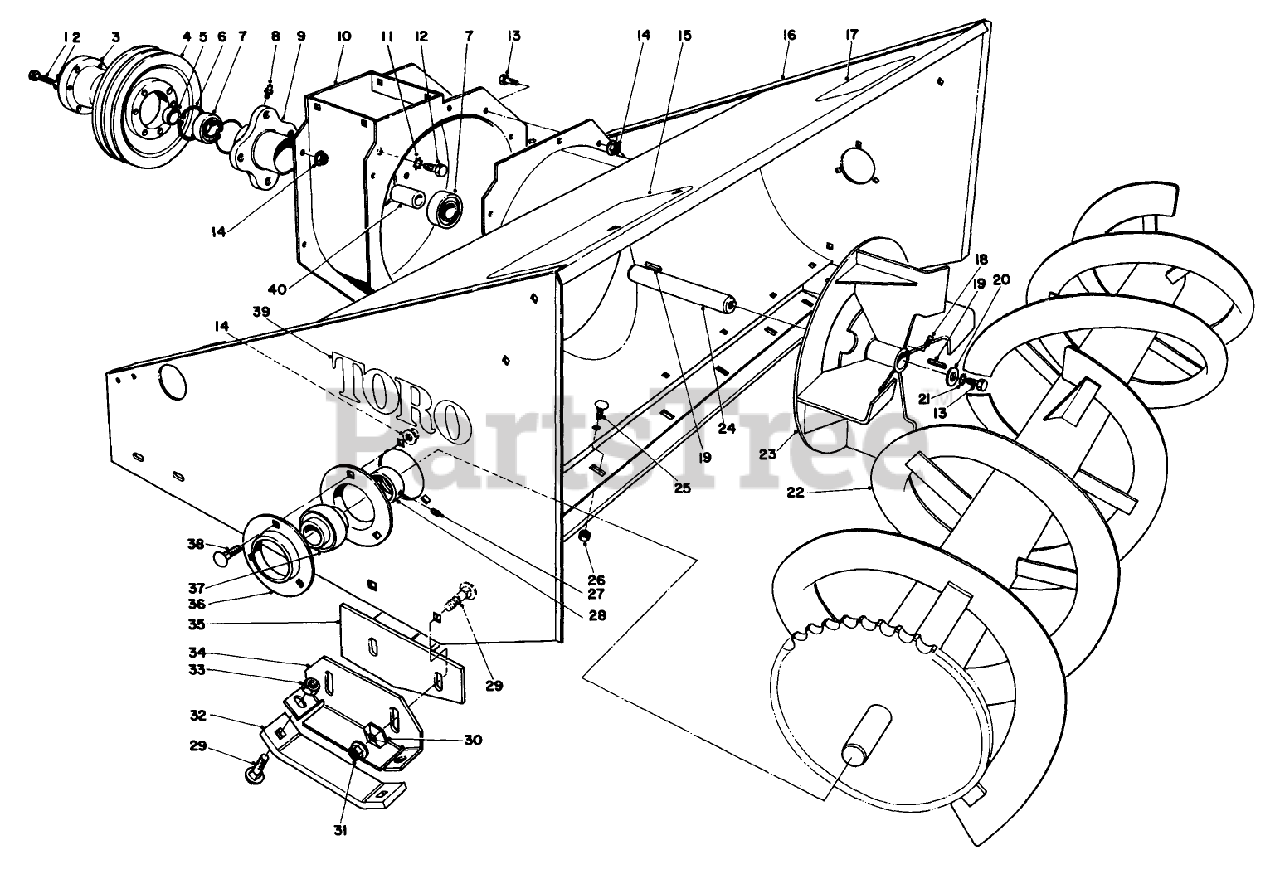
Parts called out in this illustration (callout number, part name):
1	SCREW-HH
2	WASHER-LOCK
3	Hub-"QD" (Incl. Ref.#1 & 2)
4	Pulley-"QD"
5	SPACER
6	RETAINING RING
7	BEARING
8	FITTING-LUBE, 45 DEG
9	SPINDLE HOUSING
10	BLOWER HSG WA
11	WASHER-LOCK, EXT
12	SCREW-HH
13	SCREW-HH
14	NUT-HF
15	Decal-Rear Weight
16	Auger Housing
17	Decal-Warning
18	SCREW-SET
19	Square Key
20	WASHER
21	WASHER-LOCK
22	Auger
23	IMPELLER WA 60096
24	IMPELLER SHAFT
25	SCREW-CARR
26	NUT-LOCK, NI
27	SCREW-SET, HSH
28	COLLAR-LOCK, BEARING
29	BOLT-CARR
30	LOCKWASHER-PYRAMID
31	FLANGE NUT W/LG FLG
32	SKID SHOE R
33	NUT-LOCK, CONE
34	SKID MTG PLT
35	SCRAPER WA
36	FLANGE
37	Bearing (Incl. Ref.#27 & 28)
38	SCREW-CARR
39	DECAL
40	SLEEVE 16107
